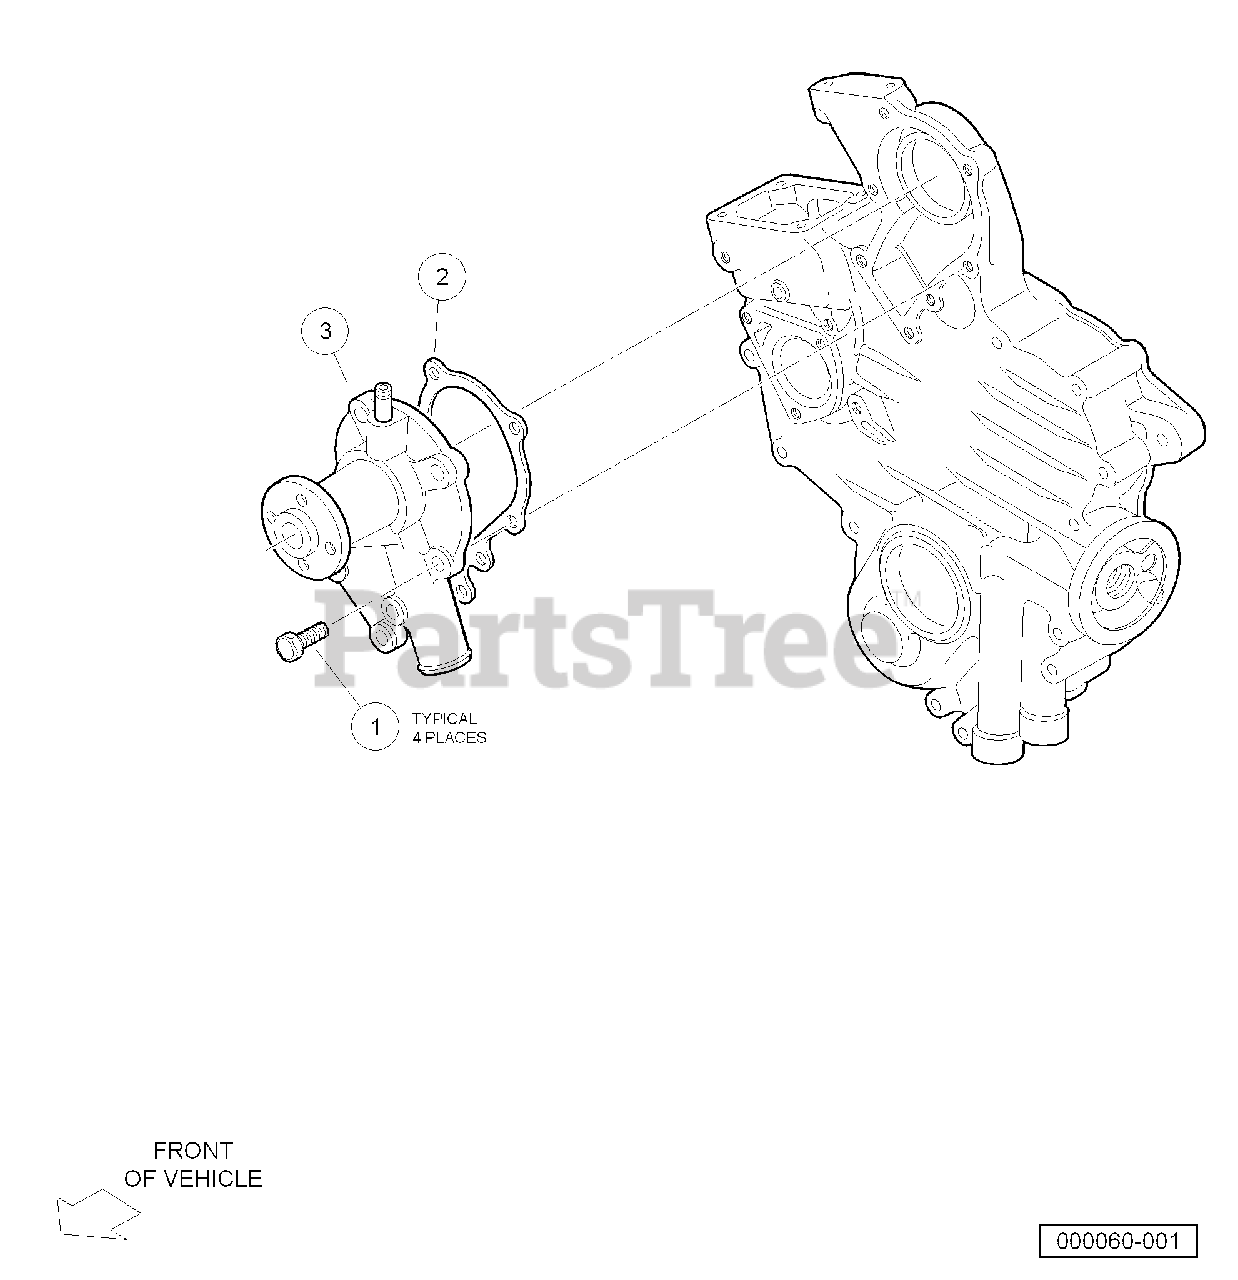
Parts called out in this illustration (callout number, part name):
1	Bolt, M6 X 1 X 22
2	Gasket, Water Pump, D722
3	Water Pump Assembly
